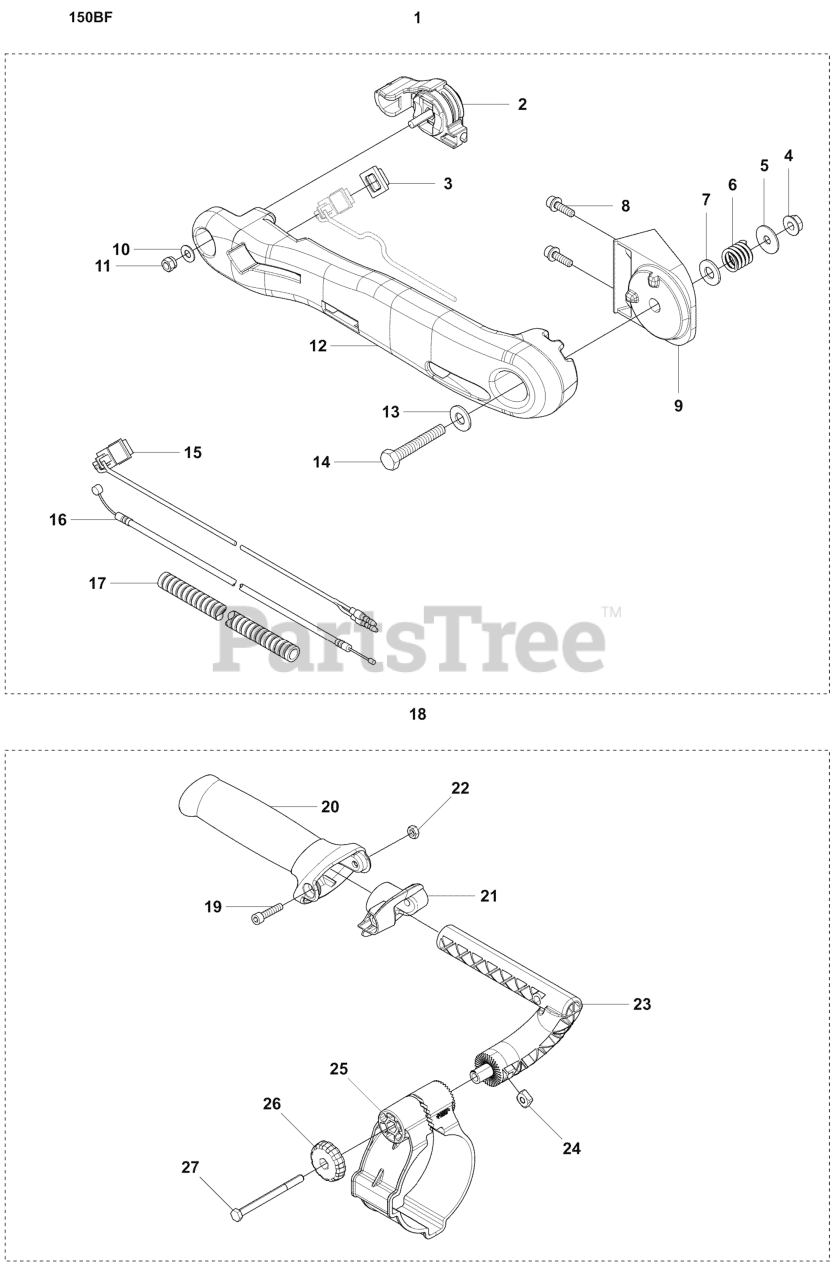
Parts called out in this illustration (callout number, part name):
1	HANDLE ASSY
2	LEVER
3	CAP
4	NUT
5	WASHER
6	SPRING
7	WASHER
8	SCREW
9	RP_BRACKET
11	NUT
12	ARM
13	WASHER
14	BOLT
15	KILL SWITCH
16	CABLE COMP
19	SCREW
23	BRACKET
25	HOLDER TH
